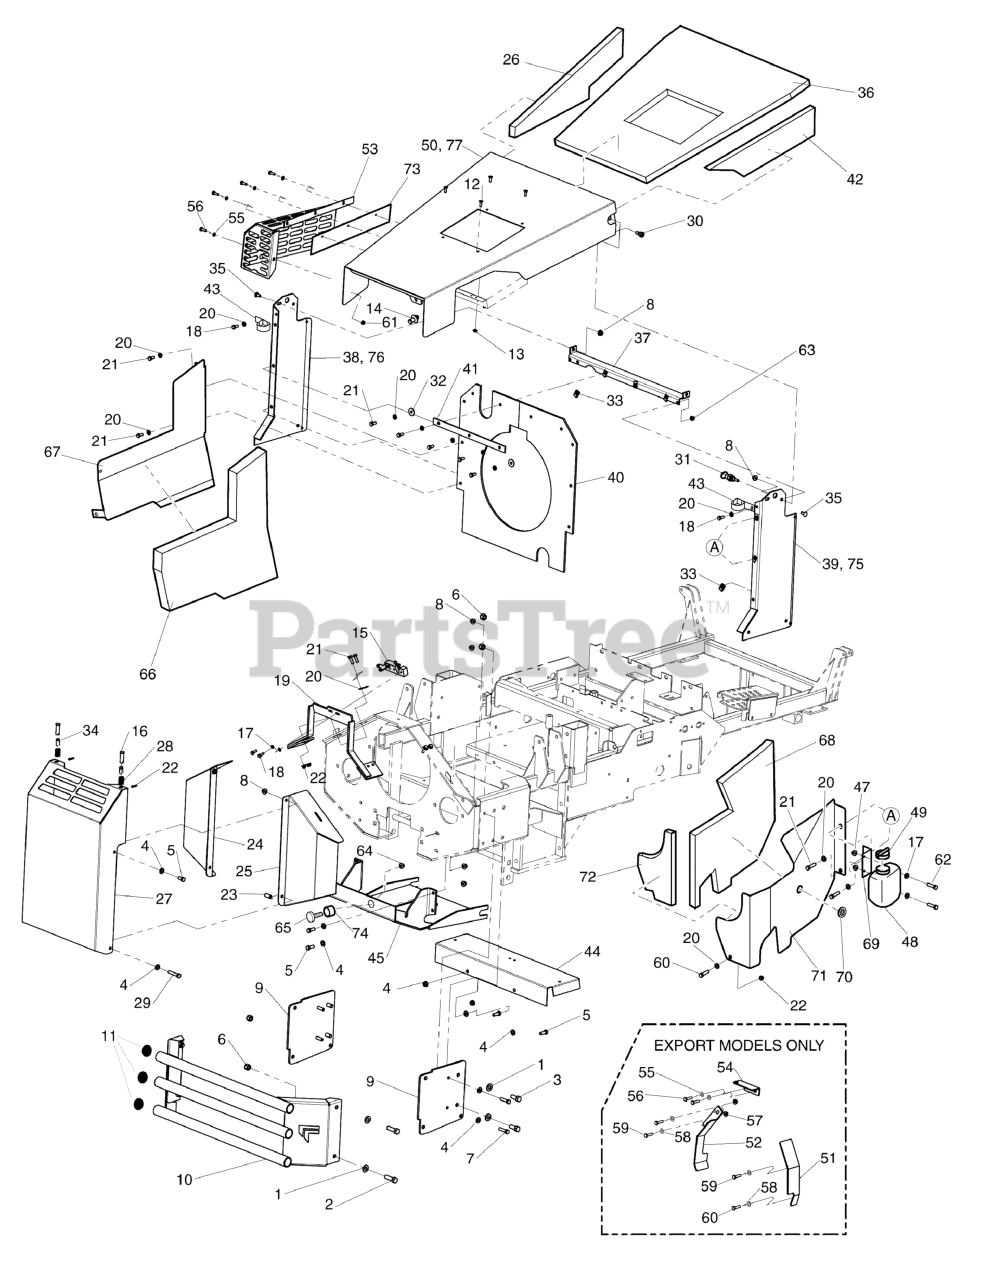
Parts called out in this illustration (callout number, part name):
1	WASHER, 1/2 SAE
2	BOLT, 1/2-20 X 1-3/4" GD8 CZ
3	BOLT, 1/2-20 X 1-1/4" GD5 CZ
4	WASHER, 3/8 SAE
5	BOLT, 3/8-16 X 1" GD5 CZ
6	NUT, Hex, Nylon Lock, 1/2-20
7	BOLT, 3/8-16 X 1-1/4" GD5 CZ
8	NUT, 3/8-16 HEX NYLOCK FLANGE
9	PLATE, BUMPER MOUNT - RED
10	WELD, BUMPER, SERVICE IS4500 - RED
11	PLUG, PANEL, 1.25 - BLACK
12	SCREW, 1/4-20 X 1/2" ALLEN BH
13	NUT, 1/4-20 NYLOCK FLANGE
14	BOLT/WASHER ASM HOOD LATCH
15	HOOD LATCH, IS5000
16	BUMPER, RUBBER, 5/16-18
17	WASHER, 1/4 SAE
18	BOLT, 1/4-20 X 3/4", GD5
19	WELD, MOUNT HOOD LATCH - RED
20	WASHER, 5/16" SAE
21	BOLT, 5/16-18 X 1" GD5 YZ
22	NUT, 5/16-18 HEX NYLOCK FLANGE
23	SPACER, .38 X .50 X 1.00
24	WELD, BUMPER SIDE LH IS5000 - RED
25	WELD, BUMPER SIDE RH IS5000 - RED
26	FOAM BAFFLE, HOOD - LEFT
27	WELD, CENTER BUMPER IS5000 - RED
28	SPRING, HOOD LATCH
29	BOLT, 3/8-16 X 1-3/4" GD5 CZ
30	BOLT, 3/8-16 X 3/8", 1/2" SHOULDER
31	PIN, LATCH, SPR LOADED-PULL ACT
32	WASHER, .34 X 1.25 X 10 GA
33	BODY CLIP, 5/16-18-7GA MATERIAL
34	SPACER, .38 X .50 X .75
35	BOLT, 5/16-18 X 3/4", CARRIAGE
36	FOAM BAFFLE, HOOD - CENTER
37	SHROUD, SUPPORT
38	WELD, SHROUD CHANNEL - LH - RED
39	WELD, SHROUD CHANNEL, RH - RED
40	SHROUD, RUBBER, IS5100Z
41	BAR, RUBBER SUPPORT SIDE
42	FOAM BAFFLE, HOOD - RIGHT
43	CLAMP, 5/16 DOUBLE, WIRE & TUBE
44	SHIELD, DEBRIS - RED
45	WELD, SKID PLATE - RED
47	NUT, 1/4-20 HEX SERR. FLANGE
48	EXPANSION TANK
50	WELD, HOOD, IS5100ZCE - RED
51	GUARD, FLYWHEEL RH
52	GUARD, FLYWHEEL LH
53	WELD, MUFFLER GUARD
54	GUARD, HOOD LATCH
55	WASHER, 1/4 SAE
56	BOLT, 1/4-20 X 3/4" GD5 YZ
57	NUT, 5/16-18 NYLOCK
58	WASHER, 5/16" SAE
59	BOLT, 5/16-18 X 1"
60	BOLT, 5/16-18 X 1-1/4"
61	NUT, 1/4-20 HEX NYLOCK FLANGE
62	BOLT, 1/4-20 X 3/4"
63	NUT, 1/4-20 HEX SERR. FLANGE
64	NUT, 5/16-18 HEX NYLON LOCK
65	BUMPER, RUBBER, 5/16-18
66	FOAM, SOUND BAFFLE, LH
67	WELD, SOUND SHIELD, LH - RED
68	FOAM, SOUND BAFFLE, RH
69	BRACKET, COOLANT RESERVOIR - RED
70	GROMMET, 3/4"
71	PLATE, SOUND SHIELD, RH - RED
72	FOAM, SOUND BAFFLE
73	PLATE, HOOD, SOUND SHIELD - RED
74	SPACER, .52 X 1.00 X .38
75	WELD, SHROUD CHANNEL - RH
76	WELD, SHROUD CHANNEL - LH
77	WELD, HOOD, IS5100Z
